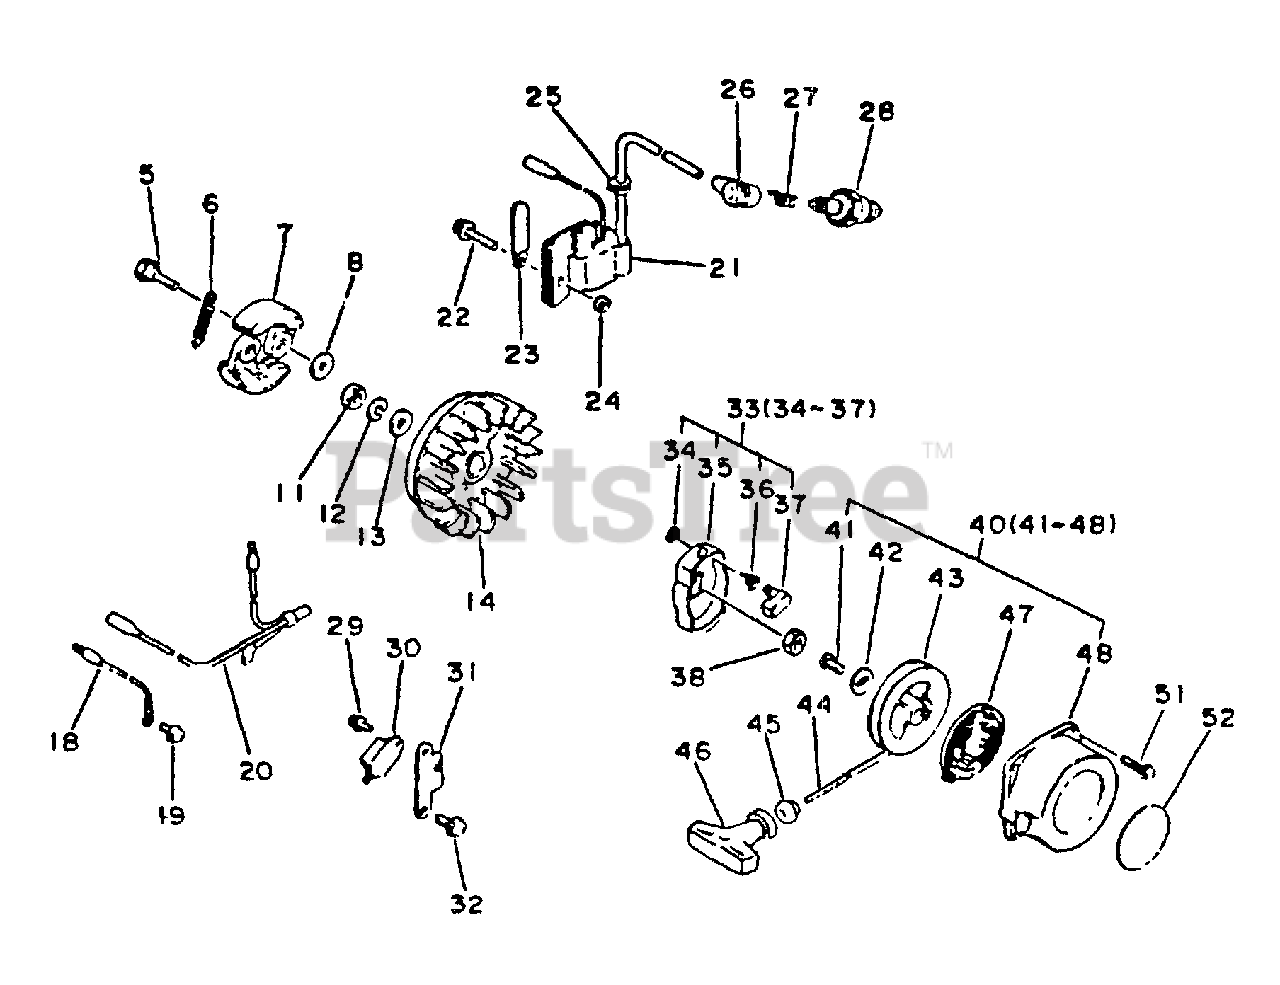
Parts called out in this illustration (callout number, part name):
5	BOLT, CLUTCH
6	SPRING, CLUTCH
7	SHOE, CLUTCH
8	WASHER 6.2×19×1.0
12	WASHER, SPRING 8
13	WASHER 8.2×17×1.6
14	FLYWHEEL
18	LEAD - GROUND L= 115
19	SCREW 5×10
21	COIL, IGNITION
22	SCREW 5×25
24	SPACER
26	CAP, SPARK PLUG
27	TERMINAL, SPARK PLUG
28	SPARK PLUG - CJ-7Y
29	SCREW 4×8
30	COIL, IGNITION
31	BRACKET, IGNITION COIL
32	SCREW 5×12
33	PAWL ASSY, STARTER
34	E-RING 4
35	PAWL CATCHER
36	SPRING, RETURN
37	PAWL, STARTER
38	NUT 8×1.25
40	STARTER ASSY
43	REEL, ROPE
44	ROPE, STARTER 4.0×880
45	GUIDE, ROPE
46	GRIP, STARTER
47	SPRING, RECOIL
48	CASE, STARTER - ORANGE
51	SCREW 4×20
52	LABEL - ECHO
